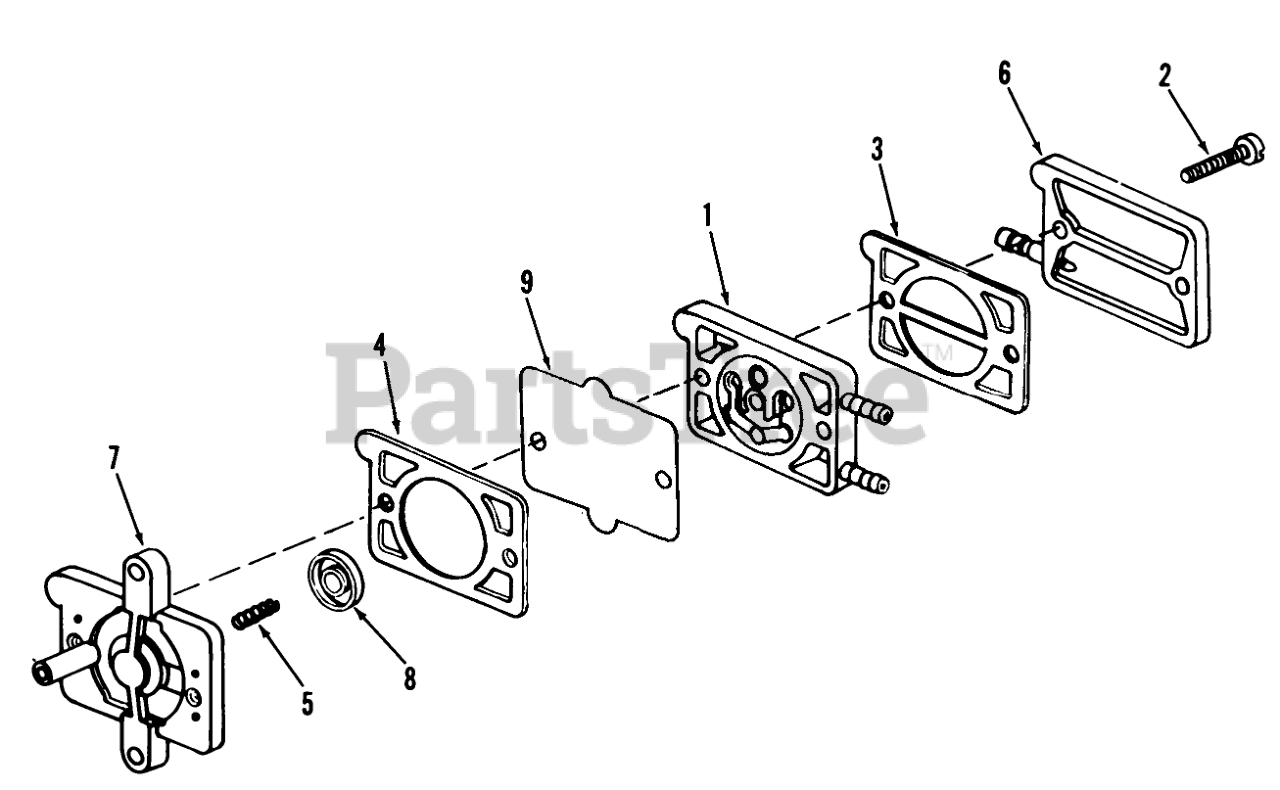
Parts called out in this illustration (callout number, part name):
1	Valve Plate Assy
2	Screw-Pump Cover
3	Gasket-Cover To Valve Plate
4	Gasket-Base To Diaphram
5	Spring-Pump To Diaphram
6	Cover-Pump
7	Base Pump
8	Plate-Pump Spring
9	Pump Diaphragm
